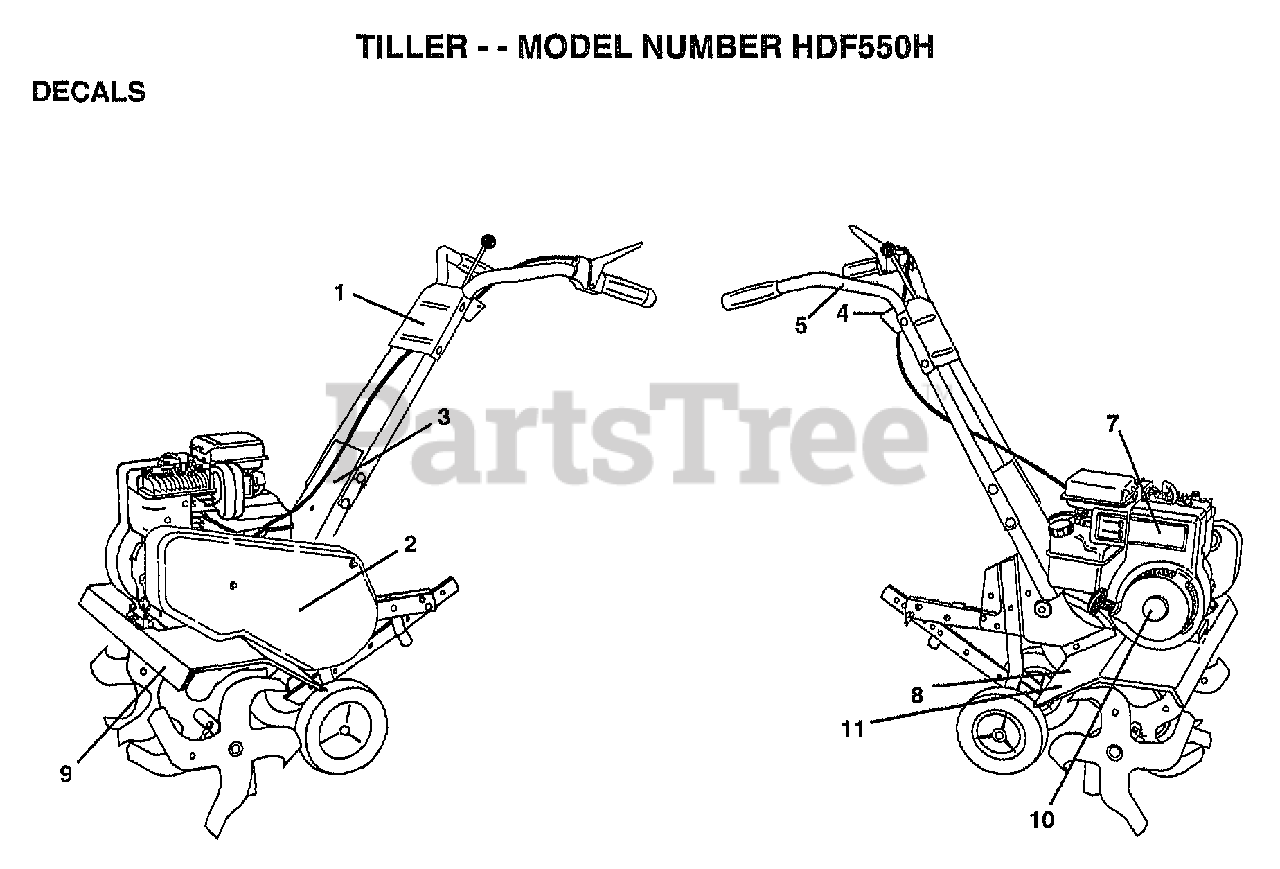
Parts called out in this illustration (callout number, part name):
1	"DECAL PANEL,CTRL"
2	"DECAL GUARD,BELT"
3	"DECAL PANEL,FORWD"
4	DECAL.PNL.CTRL.ES
5	DECAL.HAND.PLACE
8	DECAL.WARN.ROT.TI
9	"DECAL SHIELD,TINE"
11	DECAL.TINE.SHIELD
